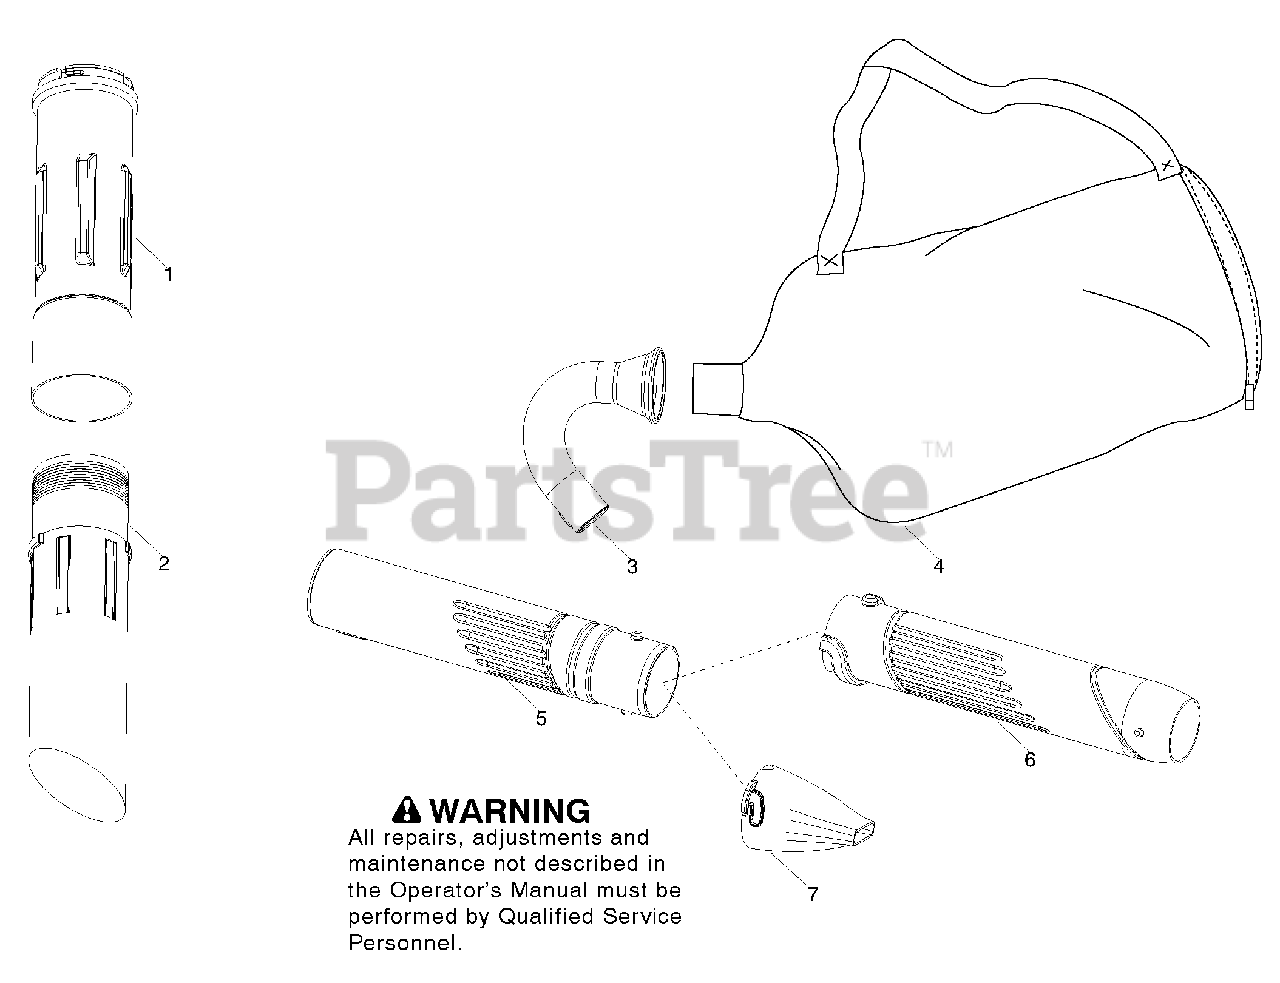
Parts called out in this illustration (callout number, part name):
1	Tube - Upper Vac
2	Tube - Lower Vac
3	Tube - J
4	Assy - Vac Bag
5	Tube - Upper Blower
6	Tube - Lower Blower
7	Nozzle - High Speed
